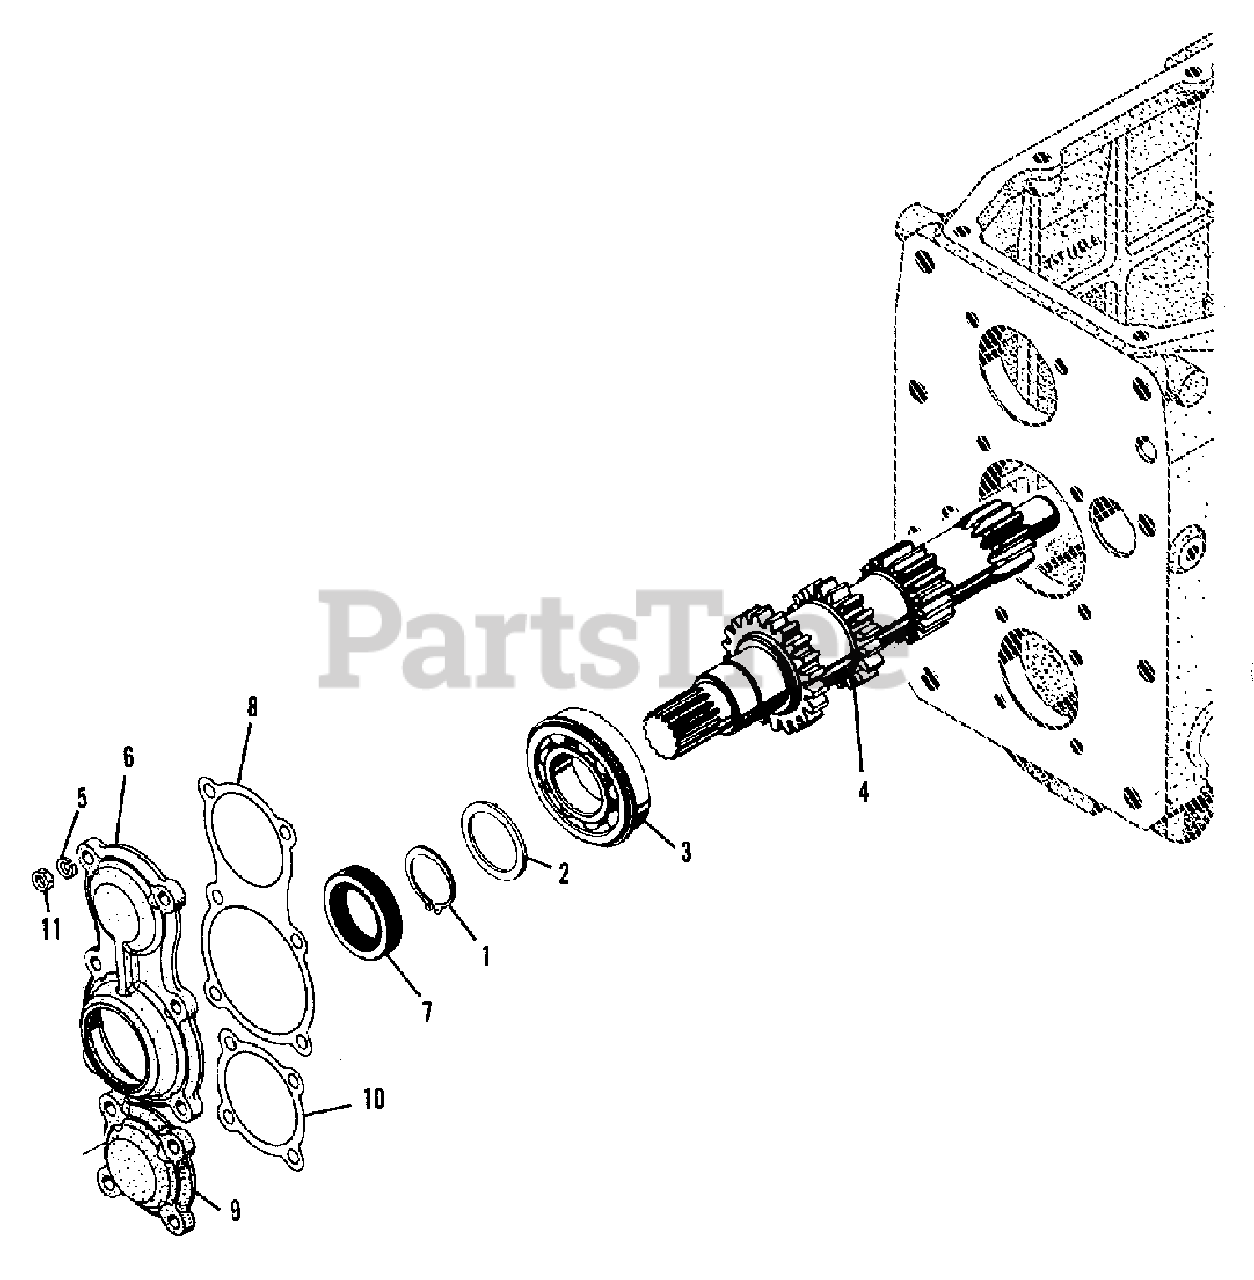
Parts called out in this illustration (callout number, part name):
1	RING, M35, snap external
2	WASHER, thrust
3	BEARING ASSEMBLY (Incl. SNAP RING)
4	SHAFT, main
5	LOCKWASHER
6	COVER ASSEMBLY, front (Incl. Item 7)
7	SEAL, oil
8	GASKET, front cover
9	COVER, P.T.O. bearing
10	GASKET, P.T.O. bearing cover
